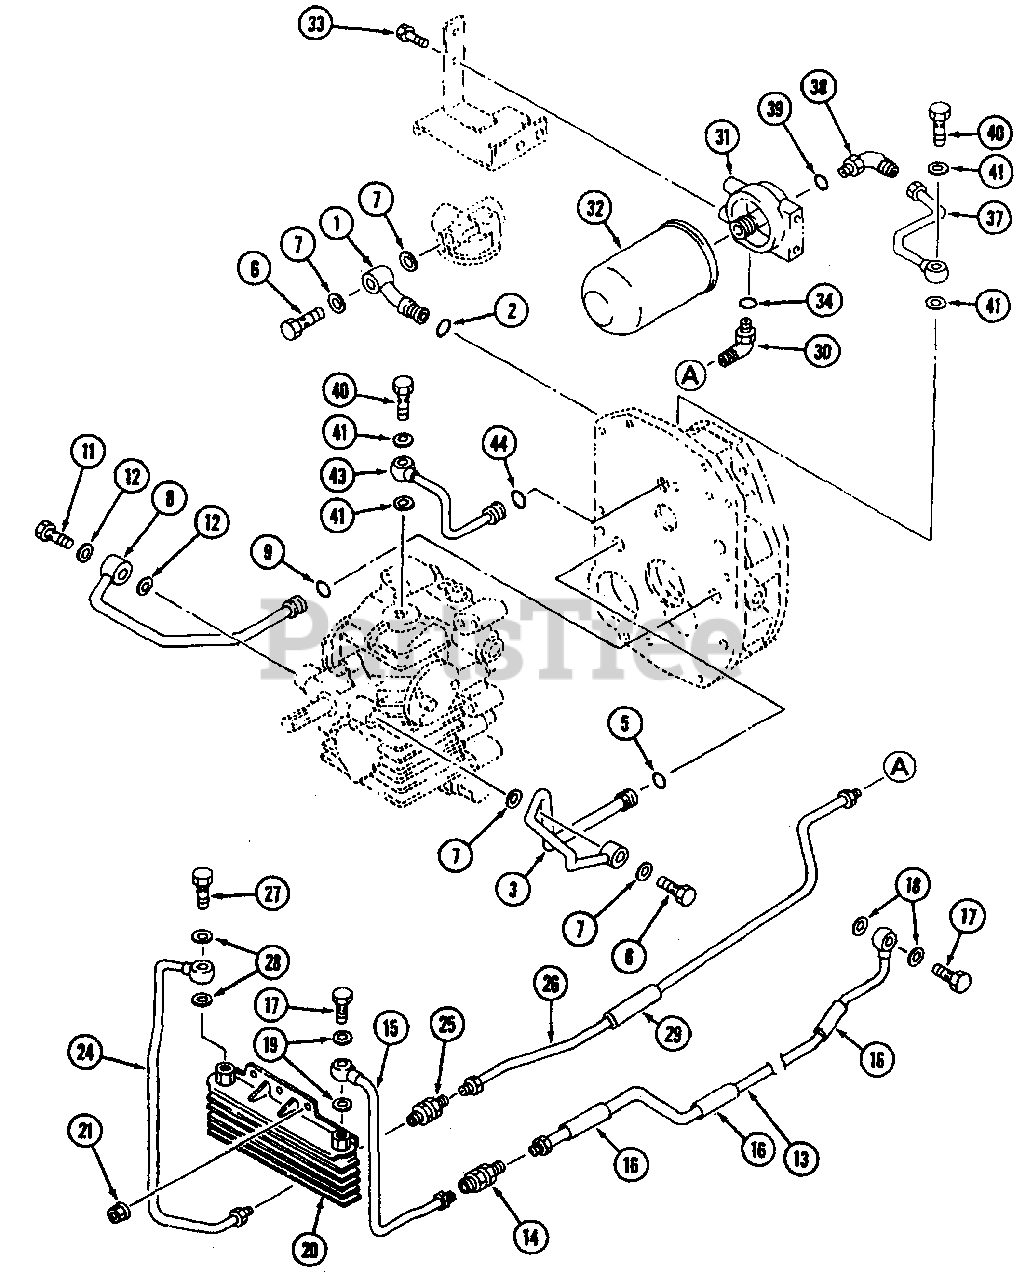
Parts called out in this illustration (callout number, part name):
7	Seal, Washer
12	Seal, Washer
13	Pipe, M Ass'y.
15	Pipe, N Ass'y.
18	Seal, Washer
24	Pipe, P Ass'y.
26	Pipe, Q Ass'y.
33	Bolt, W/Washer
37	Pipe, R Ass'y.
41	Seal, Washer
